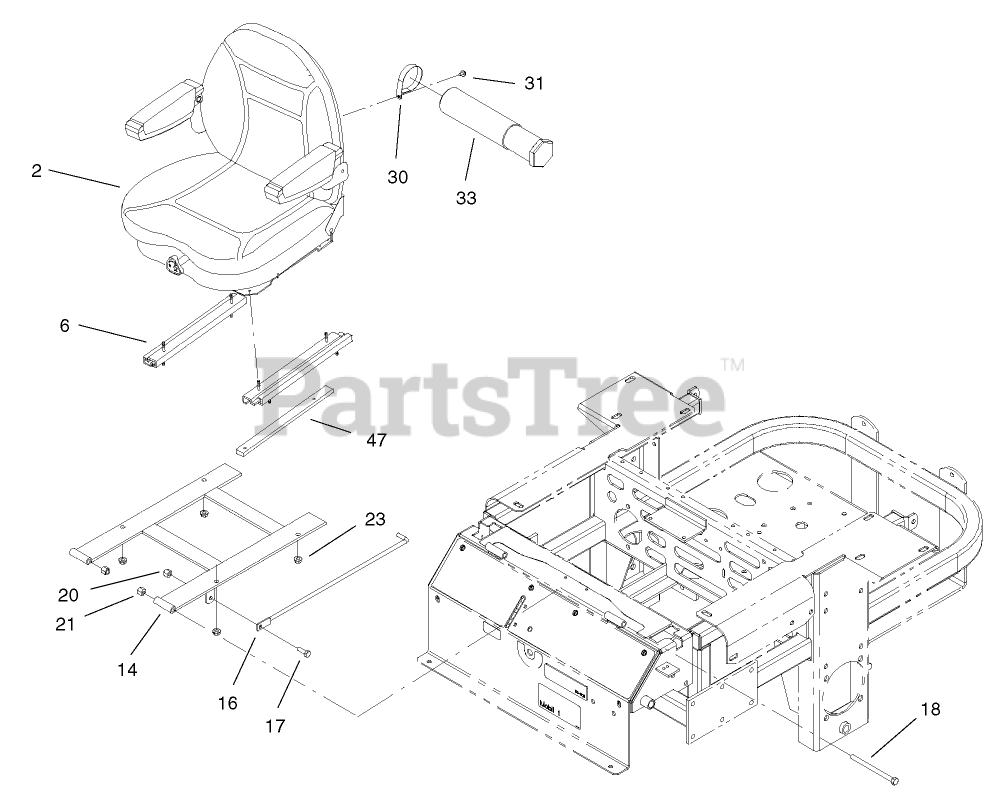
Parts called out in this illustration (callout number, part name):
2	KIT-SUSPENSION, SEAT
6	TRACK-SEAT
14	FRAME-SEAT
16	ROD-HOLDUP, SEAT
17	SCREW-HH
18	SCREW-HH
20	NUT-LOCK, NI
21	NUT-LOCK, NI
23	NUT-HF
30	CLAMP-R
31	SCREW-HWHTF
33	TUBE-MANUAL
47	STOP-SEAT
